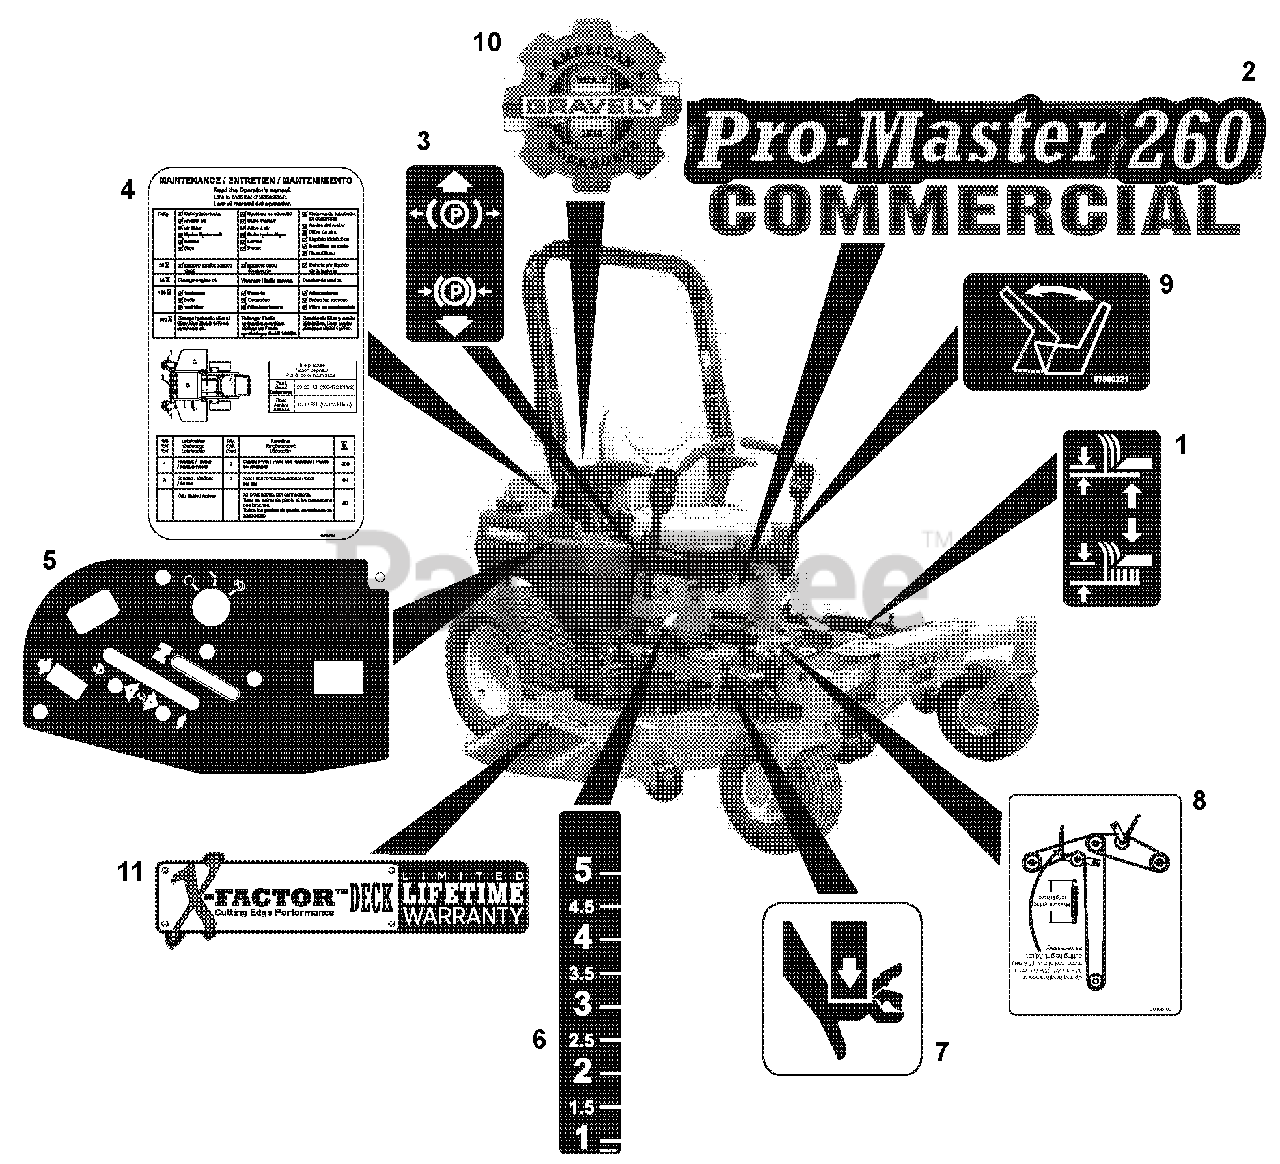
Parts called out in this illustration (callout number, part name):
1	Decal, Lift Lever
2	Decal, Pro-Master 260
3	Decal, Parking Brake Lever
4	Decal, Maintenance
5	Decal, Control Panel
6	Decal, Height of Cut
7	Decal, Pinch Point
8	Decal, Belt Diagram (992217)
9	Decal, Seat Release
10	Decal, Heritage Large
11	Decal, X-Factor Deck
